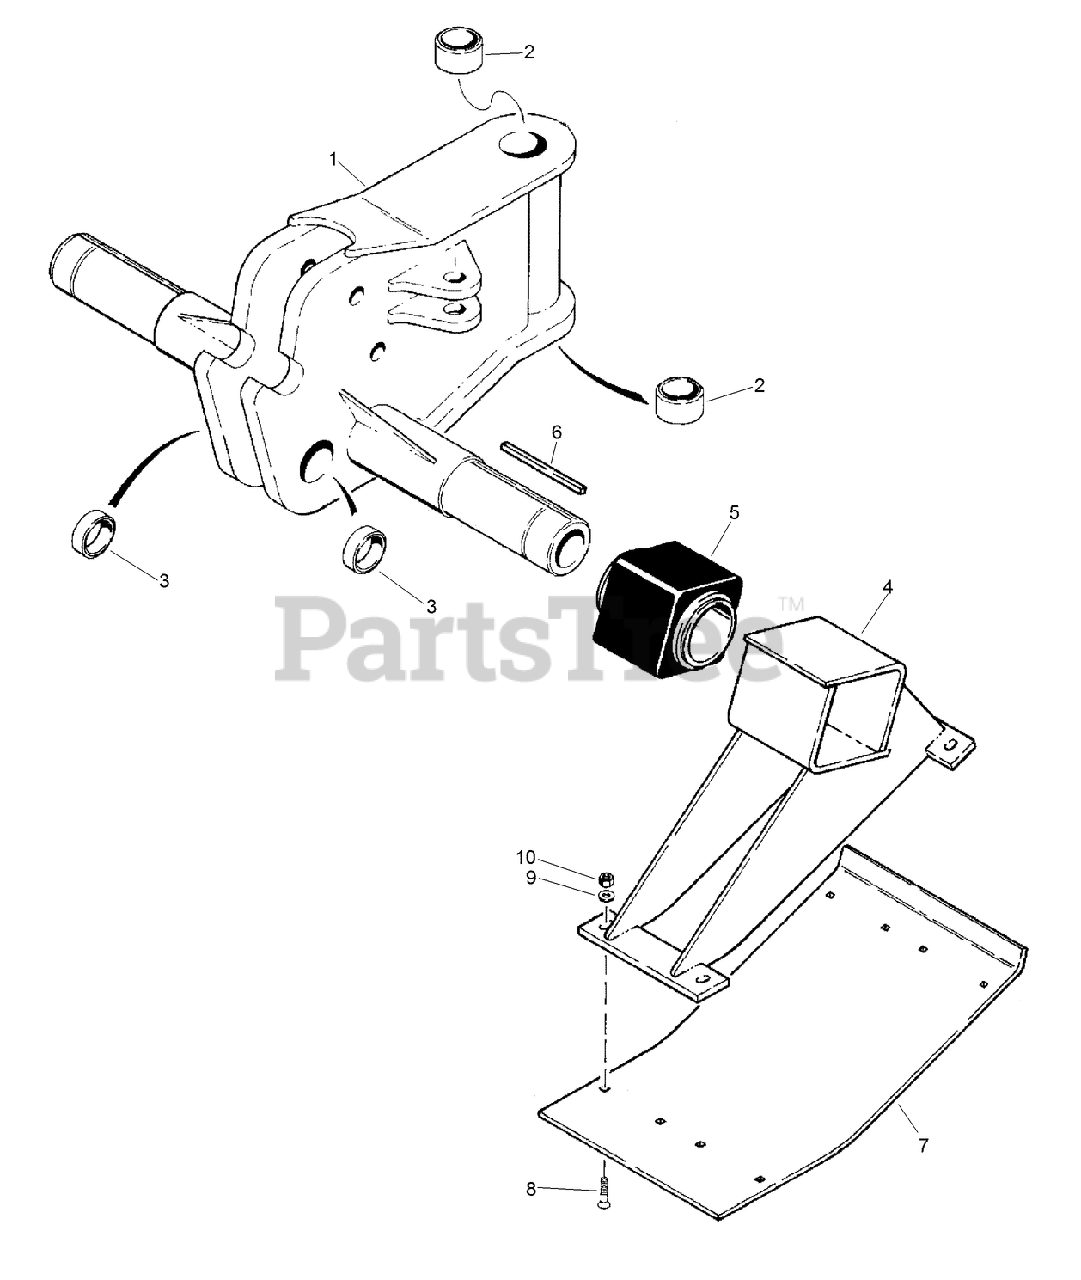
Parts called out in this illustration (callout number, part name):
1	BRACKET-plow blade mounting
1A	BRACKET-plow blade mounting
2	BUSHING
3	BUSHING
4	PLOW-SHOE ASM
5	JOINT-CENTER, BONDED RUBBER
7	PLATE-skid shoe, 12 inch wide
8	SCREW-PLOW
9	WASHER-FLAT
10	NUT-HEX
